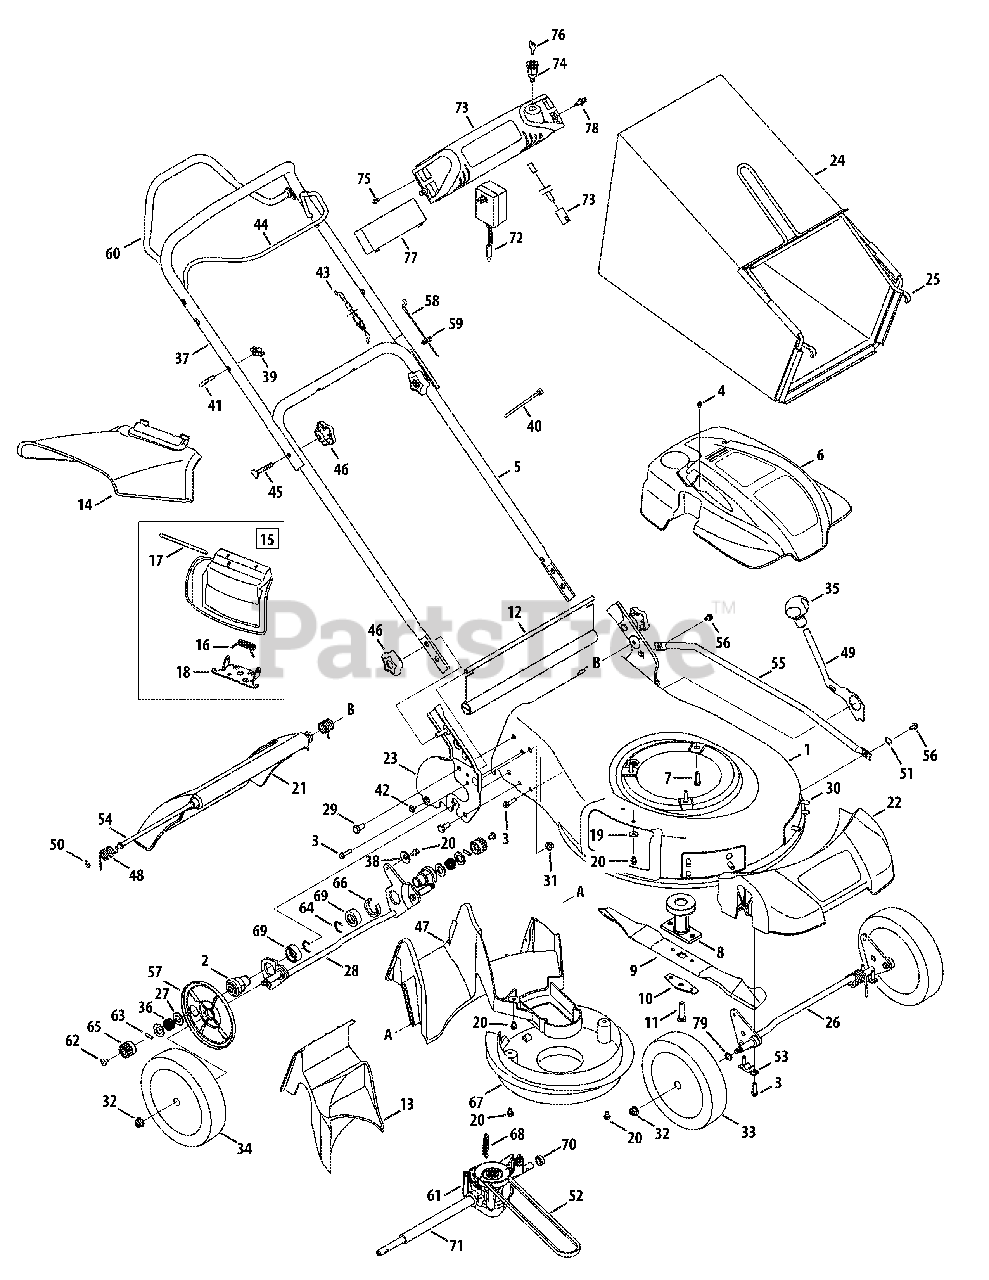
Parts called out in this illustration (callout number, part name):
2	Transmission Support Bearing
3	Screw, 1/4-15 x 1.000
4	Screw, HL, #12-16 x 1.00
5	Lower Handle
6	Engine Shroud
7	Screw, 3/8-16 x 1.00
8	Blade Adapter
9	Mulching Blade
10	Blade Bell Support
11	Screw, 3/8-24 x 1.50
12	Trailing Shield
13	Rear Mulch Plug
14	Side Discharge Chute
15	Mulch Plug (Incl. 16-18)
16	Torsion Spring
17	Hinge Pin
18	Chute Deflector Adapter
19	Belleville Washer
22	Front Cover
23	Handle Bracket - RH
23	Handle Bracket - LH
25	Grass Bag Frame
26	Front Bracket Assembly
27	Washer, Flat, .508 x 1.00 x .020
28	Self Propelled Bracket Ass’y
29	Hhcs, 5/16-18 x .625
30	Screw, 5/16-14 x .750
31	Nut, Flange Lock, 5/16-18
32	Nut, Flange Lock, 3/8-16
33	Front Wheel
34	Rear Wheel
36	Wave Spring
37	Upper Handle
38	Washer, Bell, .340 x .872 x .060
40	Cable Tie
41	Rope Guide
42	Screw, #10-16 x .500
43	Control Cable
44	Blade Control
45	Bolt Carriage, 5/16-18 x 2.0
47	Rear Baffle
48	Door Torsion Spring - RH
48	Door Torsion Spring - LH
49	Spring Lever
50	Nut, Push
51	Wshr, Wave, .385 ID x .598 OD
53	Bushing, Lock, .505 Dia. X .62
54	Rear Door Pivot Rod
55	Cross Bracket
56	Scr., Shldr., 1/4-20 x .50
57	Wheel Dust Cover
58	Drive Cable
60	Drive Control
61	Transmission
62	Screw, 1/4-20 x .390
63	Dowel Pin
64	Retainer Ring
65	Spur Gear - RH
65	Spur Gear - LH
66	Spacer, Clip
67	Engine Baffle
68	Exten. Spring, .429OD x 2.515
69	Bearing Support Spacer
70	Sleeve Spacer, .550ID x .340 Lg.
71	Sleeve Spacer, .550ID x 7.97 Lg.
72	Battery Charger
73	Electric Start Harness Assembly
74	Key Switch
75	Screw, #10-16 x .750
77	Battery
79	Washer, Wave, .510 x .750 x .017
